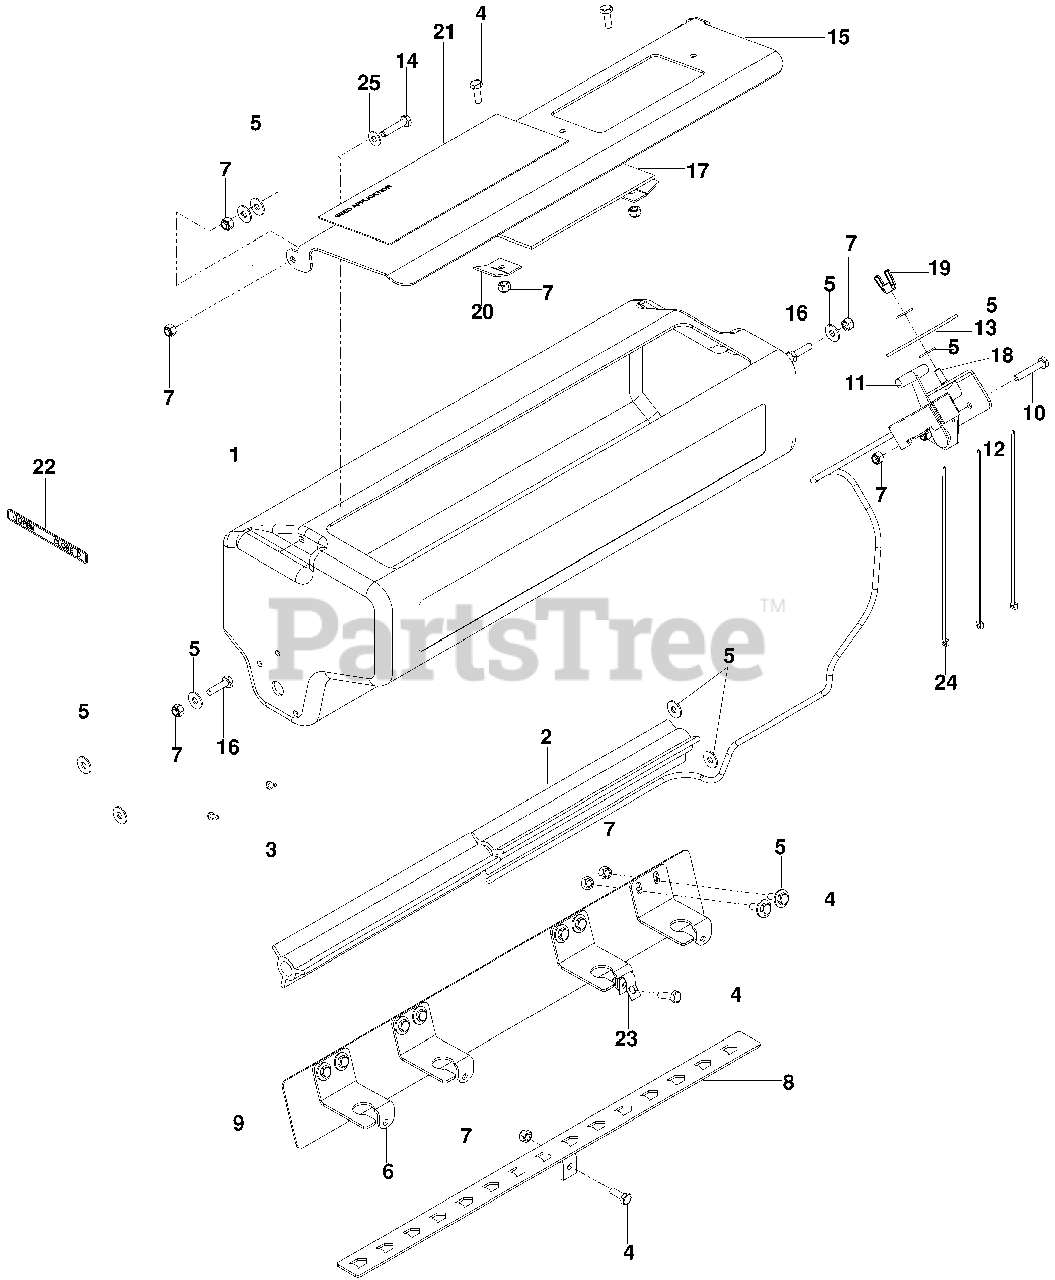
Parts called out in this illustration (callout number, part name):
3	SCREW #8-32 x 3/8 SELF TAP
4	HCS ¼-20 x ¾
7	NUT ¼-20 NYLOC
10	HCS ¼-20 x 1½
11	SEEDER CABLE
14	HCS ¼-20 x 1¼
16	HCS ¼-20 x 1
17	SEED WINDOW
18	RHSNB ¼-20 x ¾ GR2
19	WINGNUT ¼-20, NYLOC
20	WINDOW CLIP
21	DECAL, SEED APPLICATION
22	DECAL, OPEN CLOSE
23	CABLE CLAMP
25	WASHER ¼ SAE
